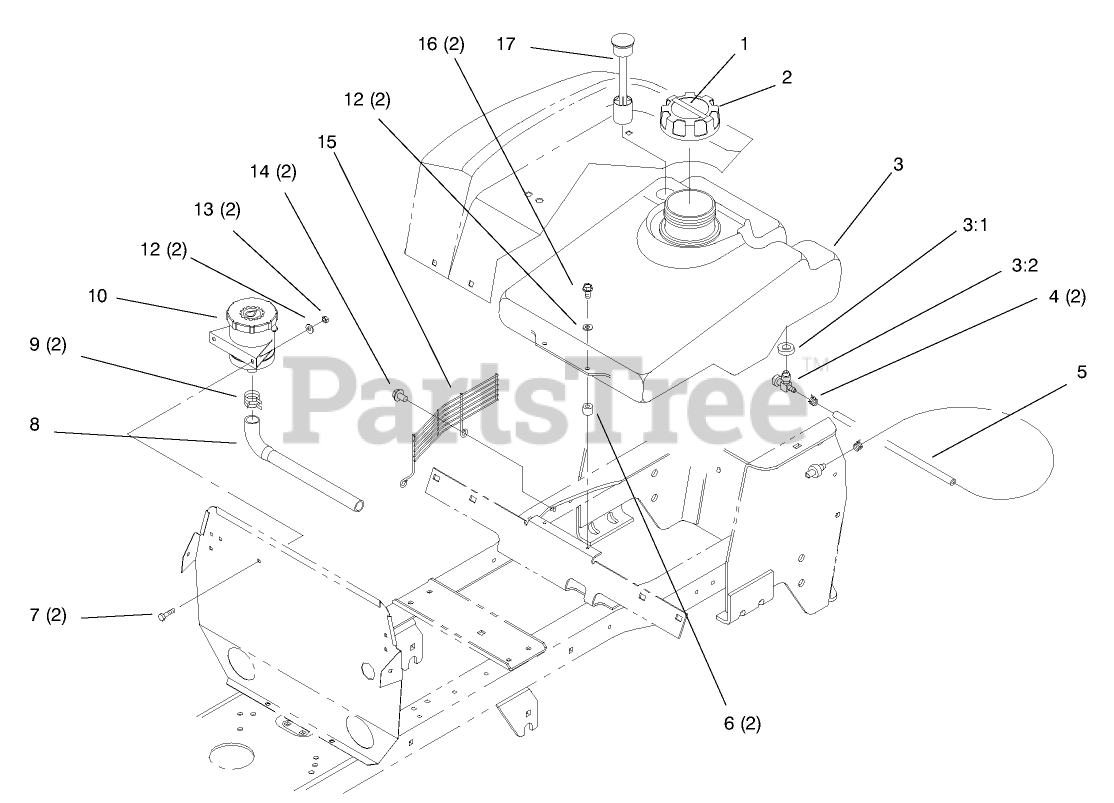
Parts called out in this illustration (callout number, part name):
2	GAS CAP ASM
4	CLAMP-HOSE
6	SPACER - FUEL TANK
7	SCREW-HH
8	HOSE - HYDRO
9	CLAMP-HOSE
12	WASHER-FLAT
13	NUT-LOCK, NI
14	SCREW-HWHTF
16	SCREW-HH
17	SENSOR-FUEL, LOW
17:1	SEAL - FUEL SENDER
17:2	Sensor-Fuel Level
